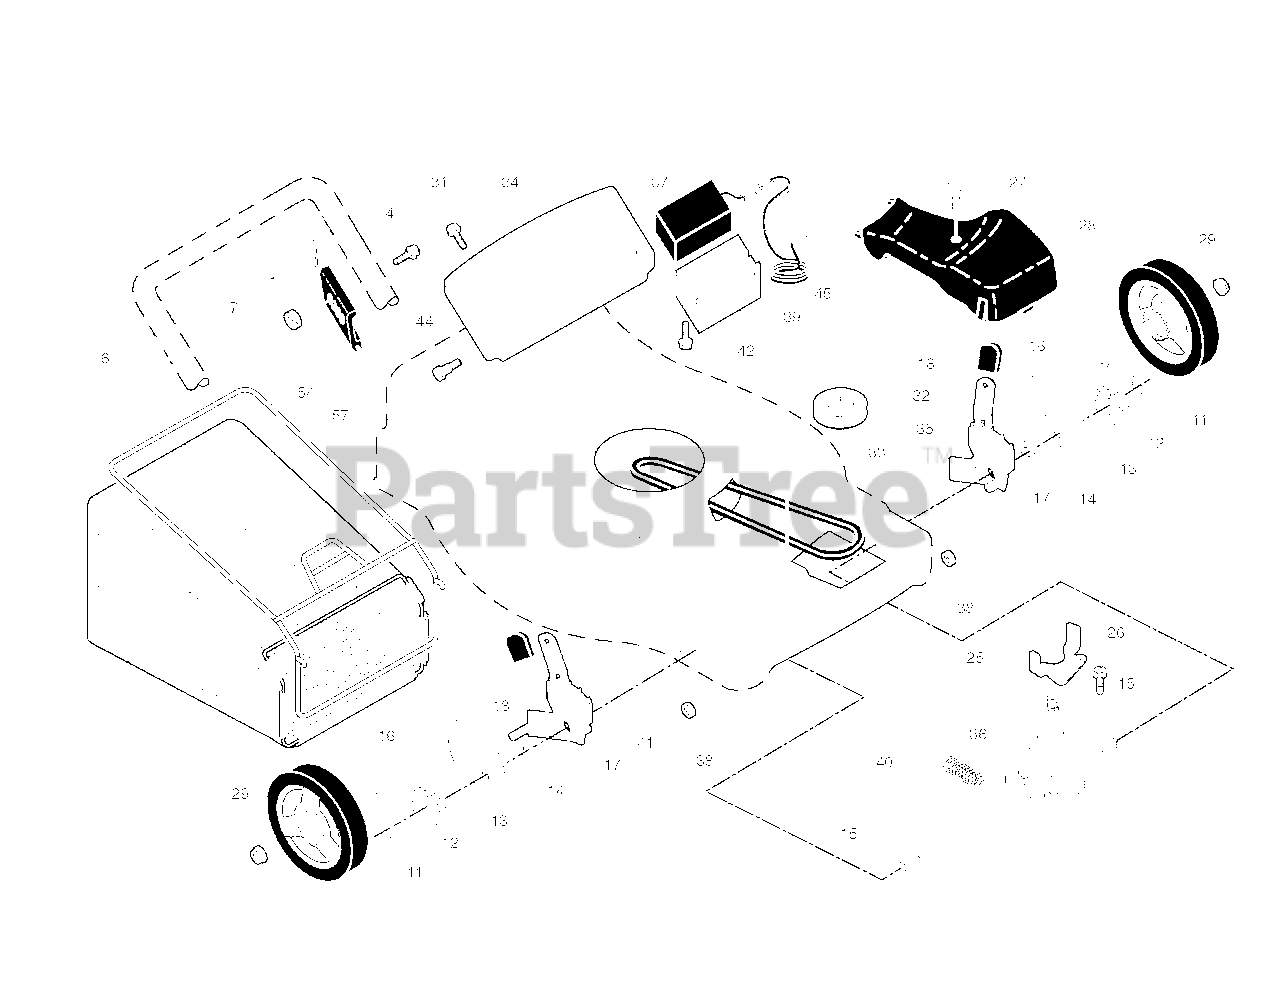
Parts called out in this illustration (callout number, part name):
1	CABLE.DR.VS.BOLT-ON.AUTO.FGD L
6	BAIL.CONT.DR.S/S.ROUND.ORG
7	NUT.HEX.FLANGE.1/4
11	WHEEL.8X1.75.H3SPK.RAD3.GY.BU3
12	E-RING 7/16 RE
13	PINION.14.TEETH.FGD
14	COVER.DUST.WHEEL
15	PAWL, DRIVE
16	WASHER FLUT
17	RP BEARING.ASM.
18	SELECTOR KNOB
25	BRACKET.BELT.GUIDE.22+FGD.BZP
27	SCREW, HEX HD TAPPING #10-24 1
28	RP DRIVE COVER
29	NUT.HEX.FLANGE.3/8-16.LO(3 2)
31	SCREW.PAN.HEAD.#10
32	RP PULLEY.DRIVE.EZ/VAR.SCREWON
33	BELT.DRIVE.FG
34	PANEL.TRIM.21.FWGD.ES
35	KIT ADJUSTER ASM.438151.
36	TRANSMISSION.22.VS.FWGD
37	BATTERY WITH AMP CONNECTOR
38	LOCKNUT.NYLOC.1/4-20
39	BOX.BATTERY.TRIM
41	KIT ADJUSTER ASM.438148
42	SCREW.HWH.13-16X.50
44	SCREW.SHOULDER.HH.10X.281X.6
45	RP CHARGER.12V.0.1A
54	GBAG.83230247T.SIL.HUSQ.BLU
57	FRAME.GBAG.22.EZ.EMPTY.SC
